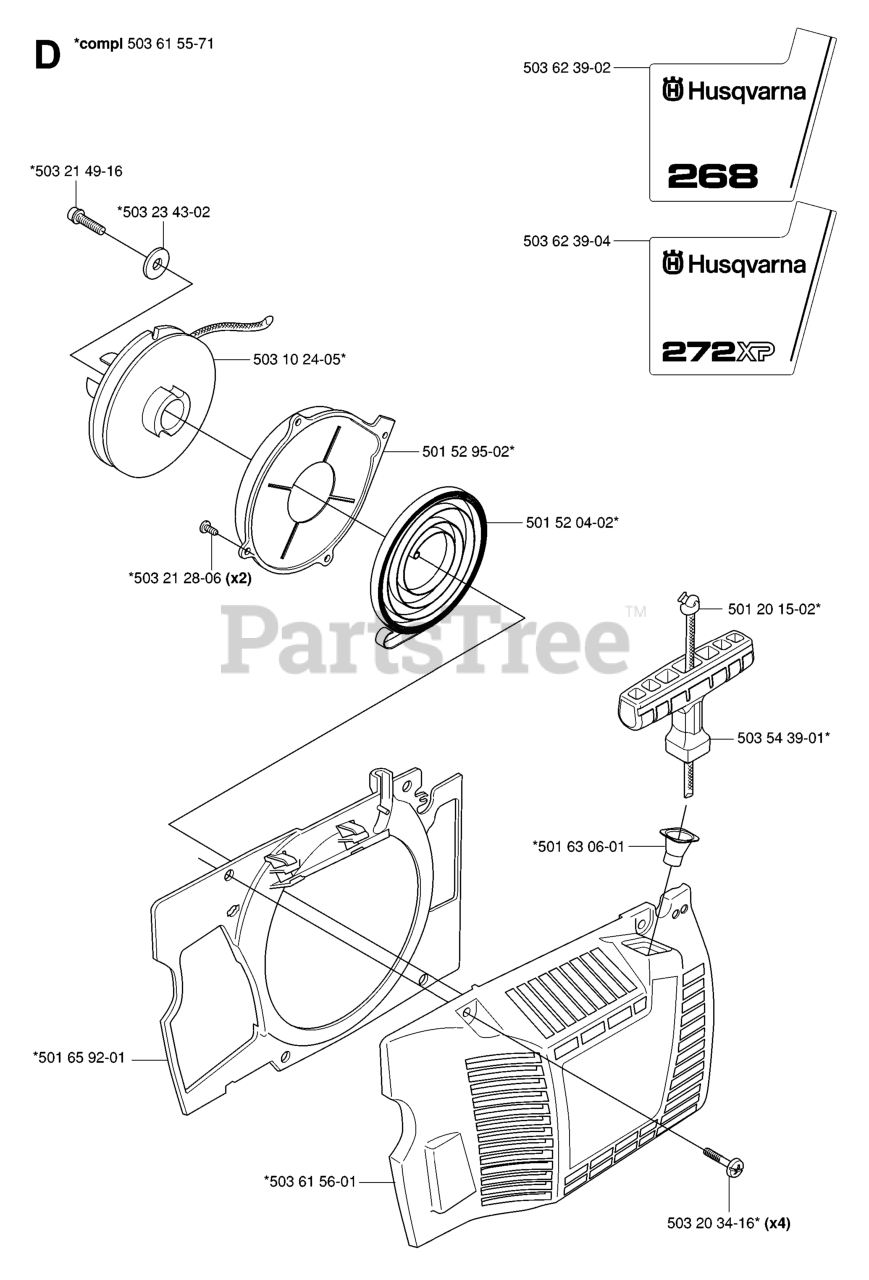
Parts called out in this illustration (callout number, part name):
1	HCS 1/4C X 2
2	KNURLED INSERT
3	DECK W/DECALS W21
4	TOP SADDLE
5	DECK BRACKET
6	BELT SHIELD
8	DESCHARGE FLAP
9	ENGINE GUARD
11	CHUTE BOTTOM
12	RHSNB, 5/16C X 3 1/4, GR5
13	SPRING TORSION
14	HANDLE BRACE, RIGHT
15	HANDLE BRACE, LEFT
16	GRASS BAG - W21
17	SCREW, 1/4-14 X 1/2, THD FORM
18	DECK FLAP - REAR
20	NUT.1/4-20.HEX.NYLOC.ZD
21	COTTER PIN 3/32 X 3/4
22	LOCKWASHER 1/4"
23	SCREW 5/16C X 1 HEX CAP
24	HCS 5/16C X 1
25	HCS 1/4 X 1
26	HCS 5/16 X 3
27	HCS 1/4C X 3/4 HCS
28	WASHER 1/4 FLAT
29	SCW 1/4-20 X 1-1/2 HEX
30	NUT 5/16 NYLOC
